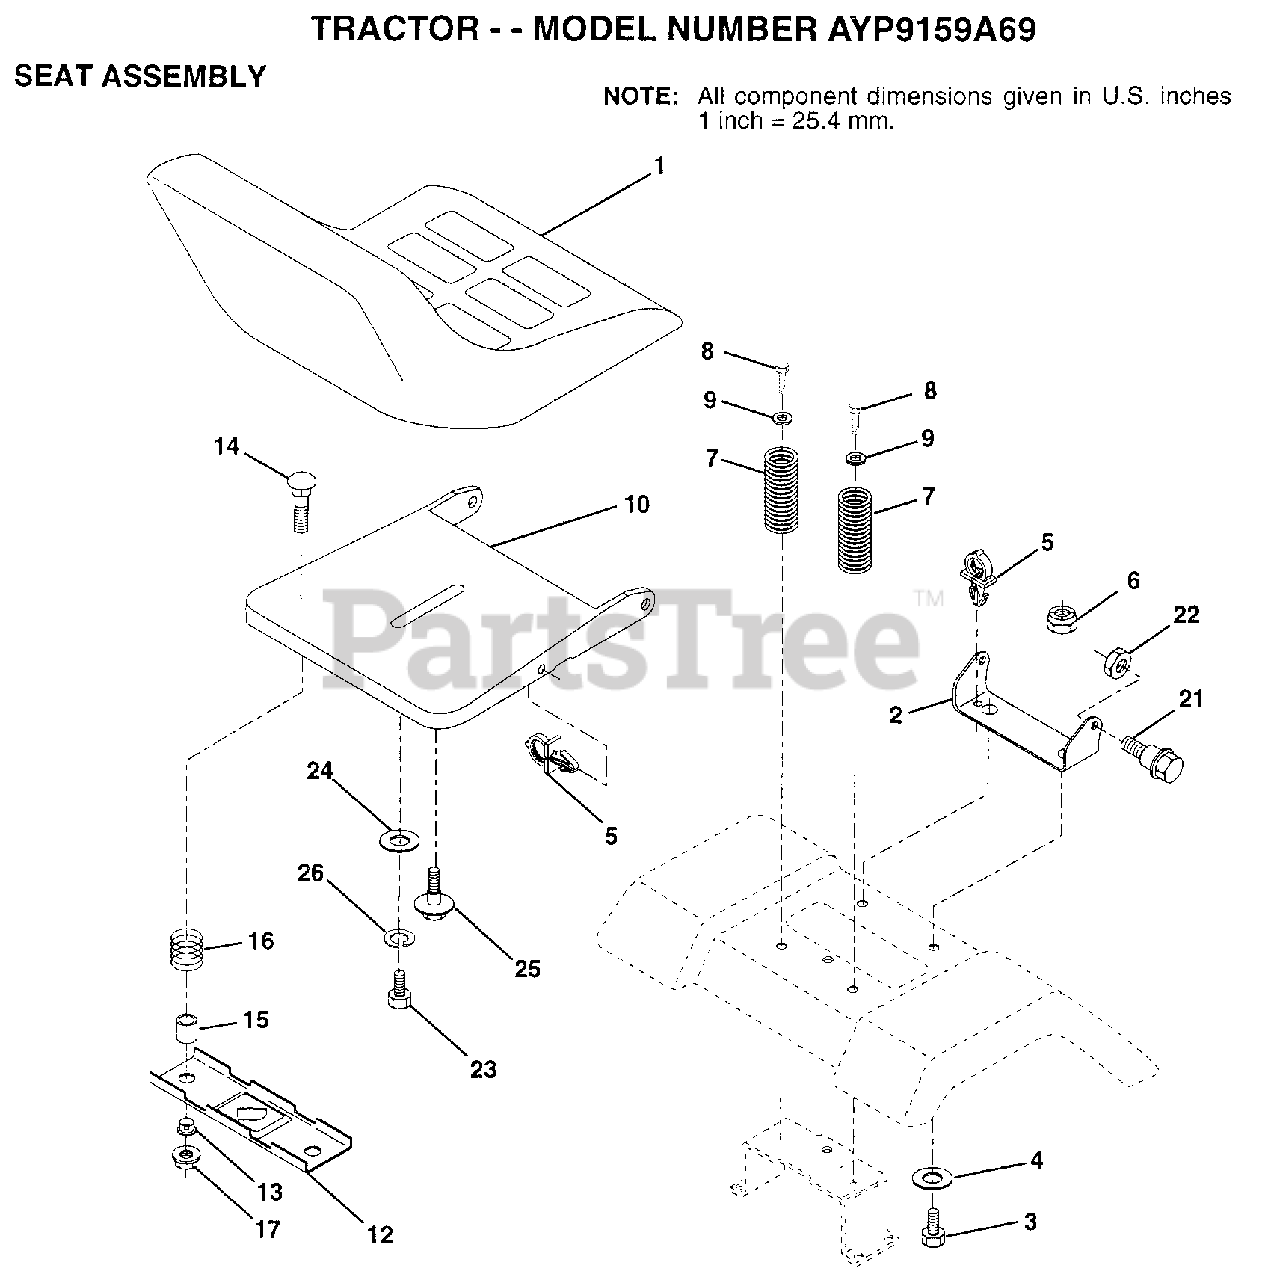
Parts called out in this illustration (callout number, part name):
1	SEAT.2400/1416.BK
2	BRACKET PVT SEAT
3	BOLT
4	WASHER PM
5	CLIP.PUSH-IN.HING
6	NUT
7	SPRING COMPRESSIO
8	SCREW GTV
9	WASHER
12	BRKT SWITCH
13	BUSHING
15	SPLIT SPACER
16	SPRING
21	BOLT.SHLD.5/16-18
22	NUT
23	BOLT
24	WASHER
25	"BOLT,SHOULDER"
26	LOCKWASHER
